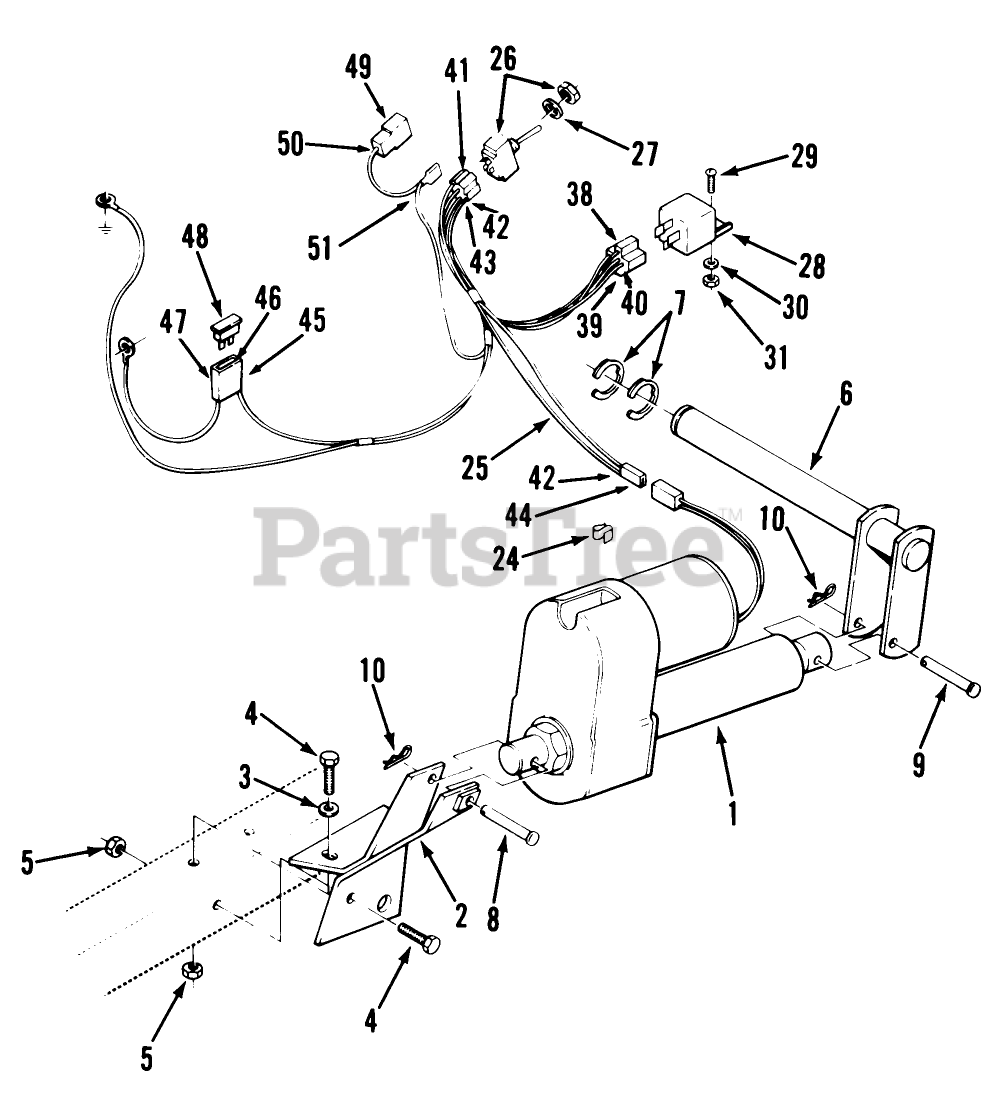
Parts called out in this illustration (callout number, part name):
8	Clevis Pin 1/2 x 2 3/4
9	CLEVIS PIN
10	Hairpin Cotter
27	Washer
28	RELAY
41	CONNECTOR 5 WAY
43	TERMINAL-TAB RCPT
44	CONNECTOR BODY *B
46	TERMINAL FUSE
48	FUSE-BLADE, 25 AMP
50	Connector Part of 5
51	Terminal
